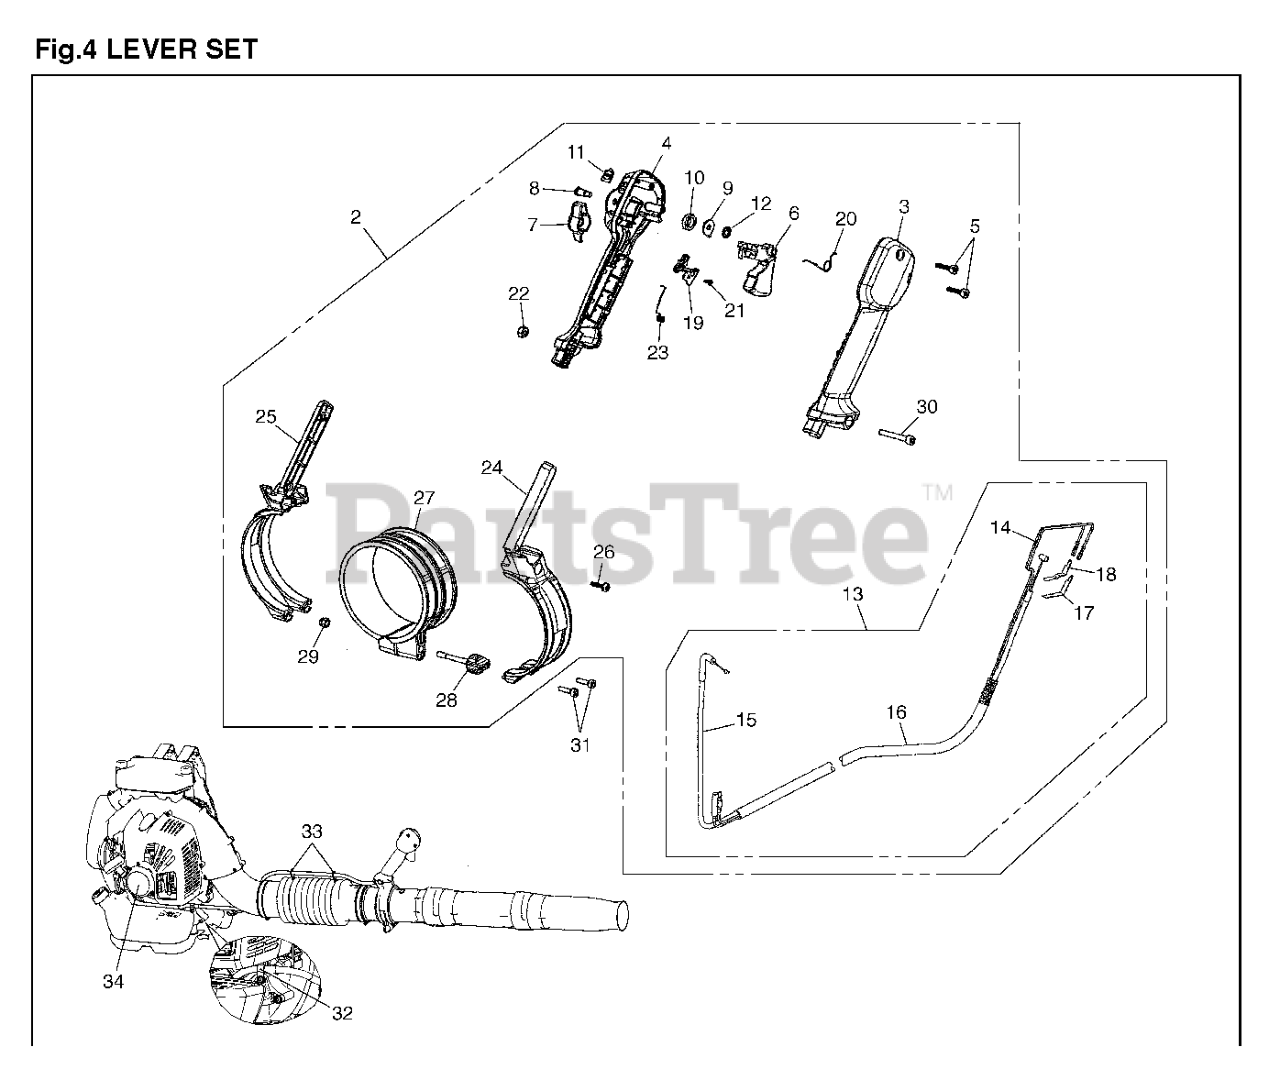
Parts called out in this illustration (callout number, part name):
2	LEVER ASSY
3	HANDLE HALF, RIGHT
4	HANDLE HALF, LEFT
5	SCREW
8	SHAFT PIVOT
10	SPRING
13	WIRING ASSY
14	CORD COMPLETE
15	CABLE, COMP
17	CONTACT SPRING
18	CONTACT SPRING
19	RETAINER
20	SPRING
24	HANDLE HOLDER, RIGHT
25	HANDLE HOLDER, LEFT
34	RECOIL LABEL
